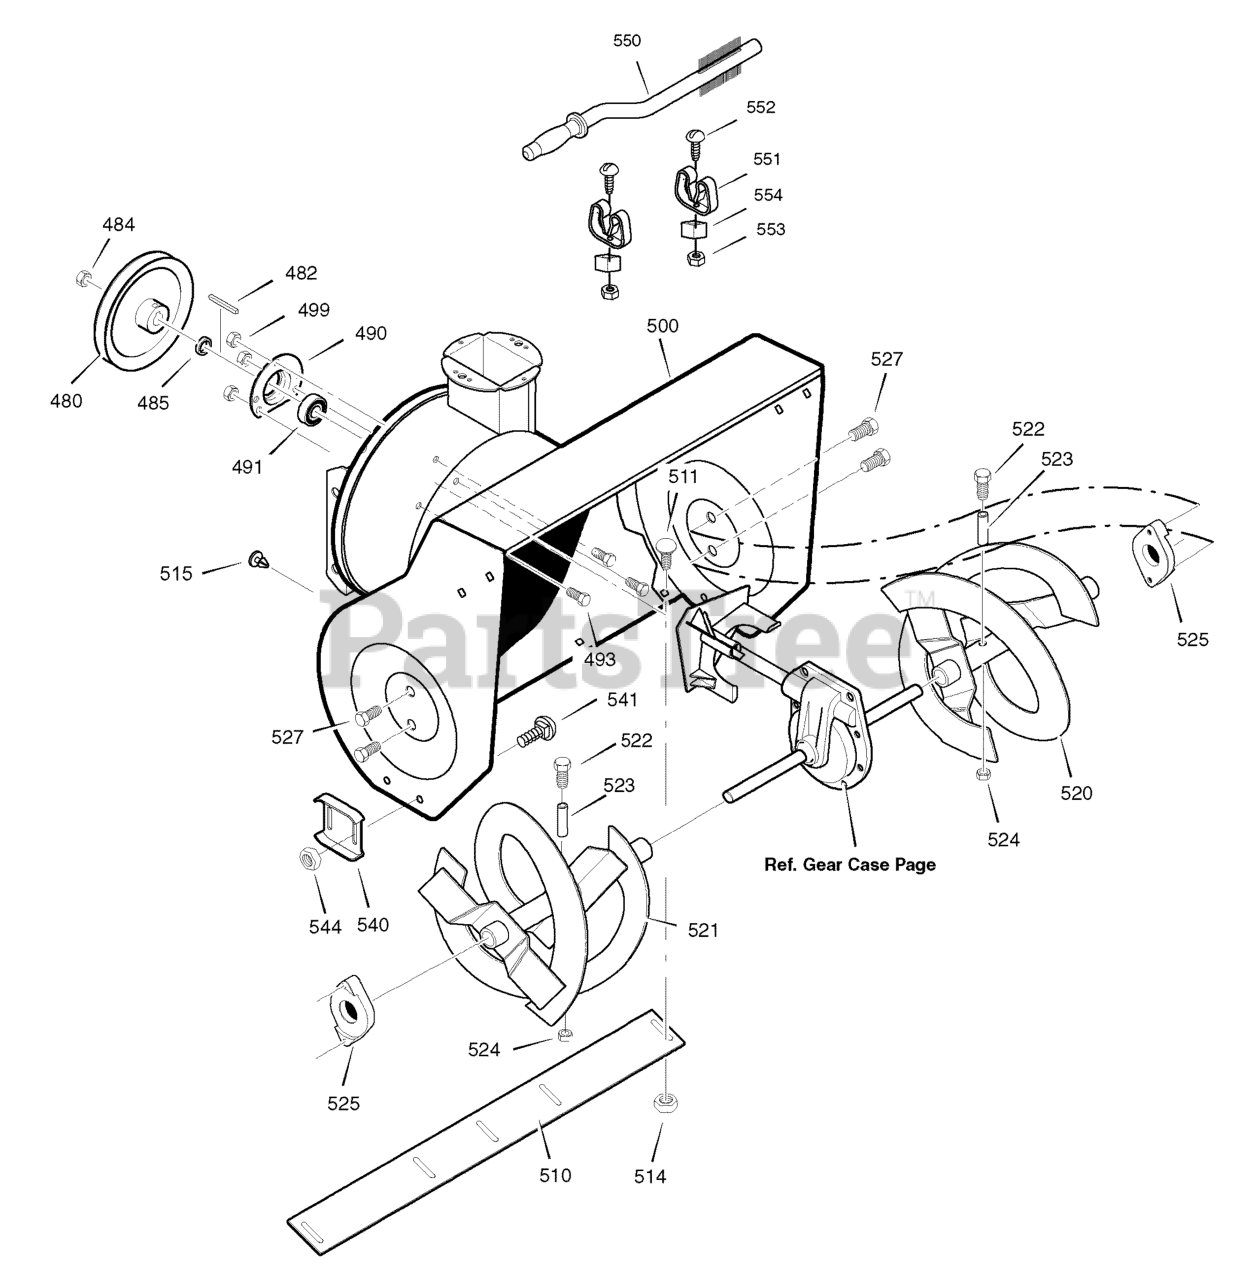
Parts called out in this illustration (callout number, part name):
480	PULLEY, 4L 8.40 OD
482	KEY, SQUARE 3/16 X 3/4
484	NUT, 1/2-20
485	SPACER, FRICTION PULLEY
490	RETAINER, BALL BRNG
491	BEARING, BALL
493	BOLT, HEX 5/16-18 X 5/8
499	NUT, 5/16-18 HEXWDFLLK
500	HOUSING, ASSY
510	BLADE, SCRAPER
511	BOLT, 5/16-18X.75
514	NUT, 5/16-18
520	AUGER, ASSEMBLY, LH
521	AUGER, ASSEMLBY, RH
522	BOLT, SHEAR
523	SPACER
524	NUT
525	BEARING, FLANGE
527	SCREW, 5/16-18 x 0.75
540	SKID, HEIGHT ADJUST
541	BOLT, 5/16-18 X .75
544	NUT, 5/16-18
550	BRUSH, CLEANOUT
551	CLIP, RETAINER
552	SCREW
553	NUT
